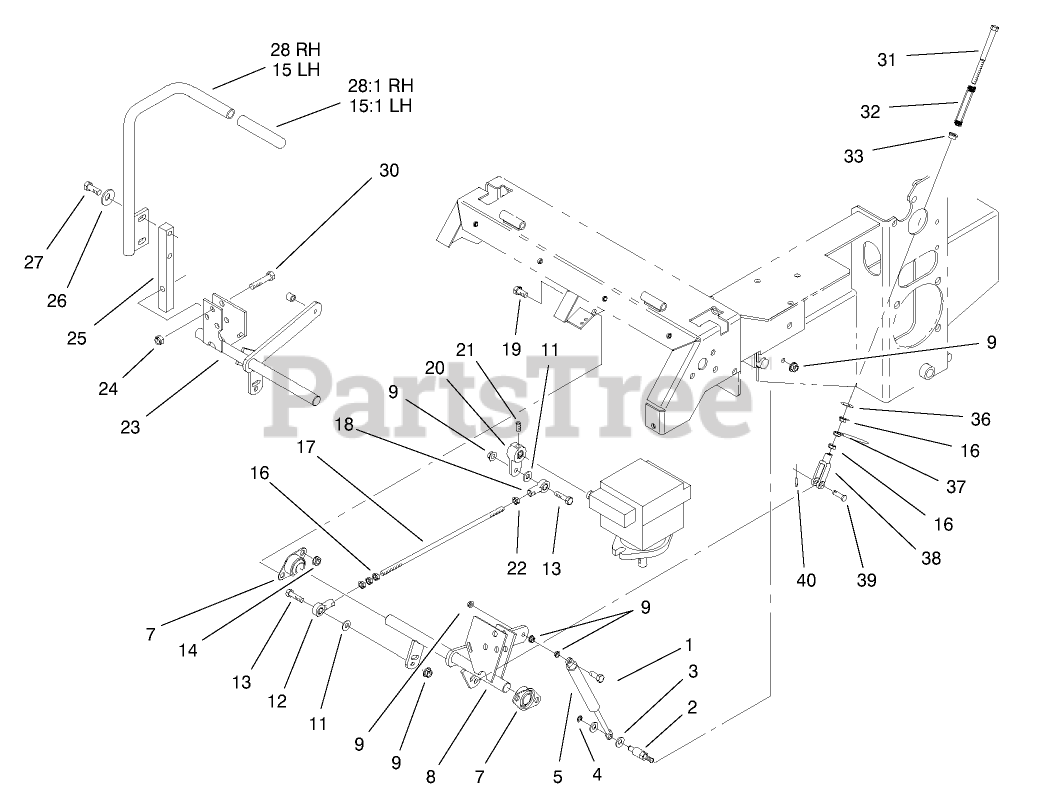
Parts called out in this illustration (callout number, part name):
1	SCREW-HH
2	PIN-DAMPER
3	WASHER-PLAIN
4	RING-RETAINING, EXT
5	DAMPER-CONTROL
7	BEARING-FLANGE, SIDE
8	LH Motion Control ASM
9	NUT-HF
11	WASHER-FLAT
12	BALLJOINT-RH
13	SCREW-HH
14	NUT-HHF, WHIZ
15	LH LEVER ASM
15:1	GRIP-CONTROL, MOTION
16	NUT-HEX
17	LINKAGE-PUMP/LEVER
18	BALLJOINT-LH
19	SCREW-HH
20	ARM-CONTROL, PUMP
21	SCREW-SET
23	RH Motion Control ASM
24	NUT-LOCK, NI
25	ARM-SHAFT, CONTROL
26	WASHER-BELLEVILLE
27	SCREW-HH
28	RH LEVER ASM
28:1	GRIP-CONTROL, MOTION
30	SCREW-HH
31	BOLT-RETURN, NEUTRAL
32	SPRING-RETURN, NEUTRAL
33	BUSHING-FLANGED
36	WASHER-FLAT
37	NUT-JAM
38	YOKE-ADJUSTABLE
39	PIN-CLEVIS
40	PIN-COTTER
